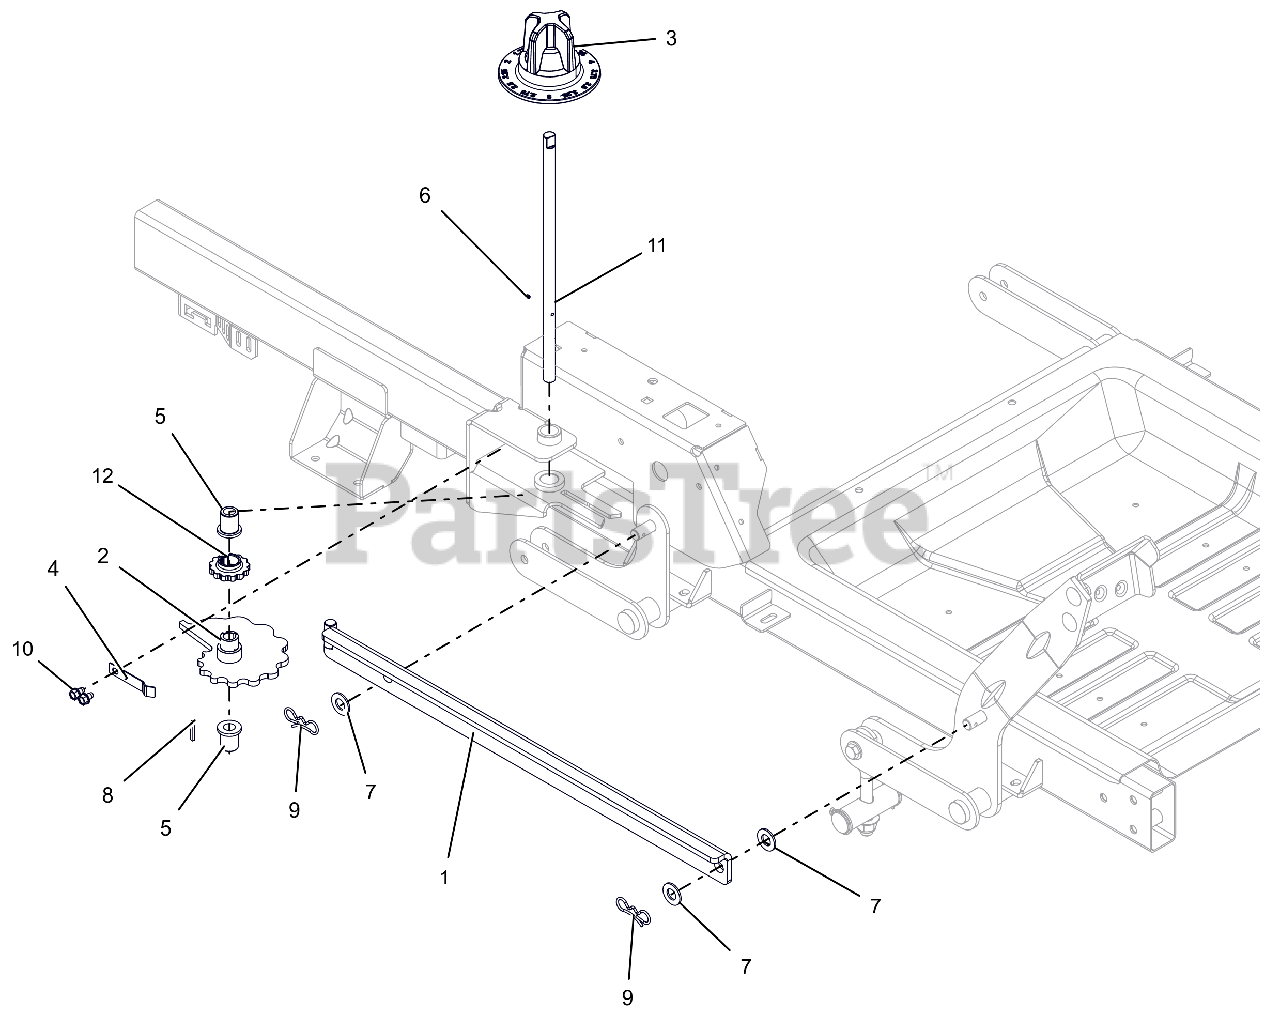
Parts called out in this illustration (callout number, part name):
1	WLDMT, HOC LINK
2	WLDMT, HOC CAM
3	KNOB, HOC DIAL
4	ARM, HOC DETENT
5	BSHG-FLG, .503X.750X.875X1.00
6	PIN-ROLL .125X1.00
7	WSHR-FL-NYL .518X1.000X.080
8	KEY, 1/8 X 1/8 X 1.0
9	PIN,BOW TIE LOCKING .091X1.875
10	@SCR-TAP .25-20X.37 HWH YWZ TR
11	SHAFT, HOC CAM IKON
12	GEAR, HOC INDEX
